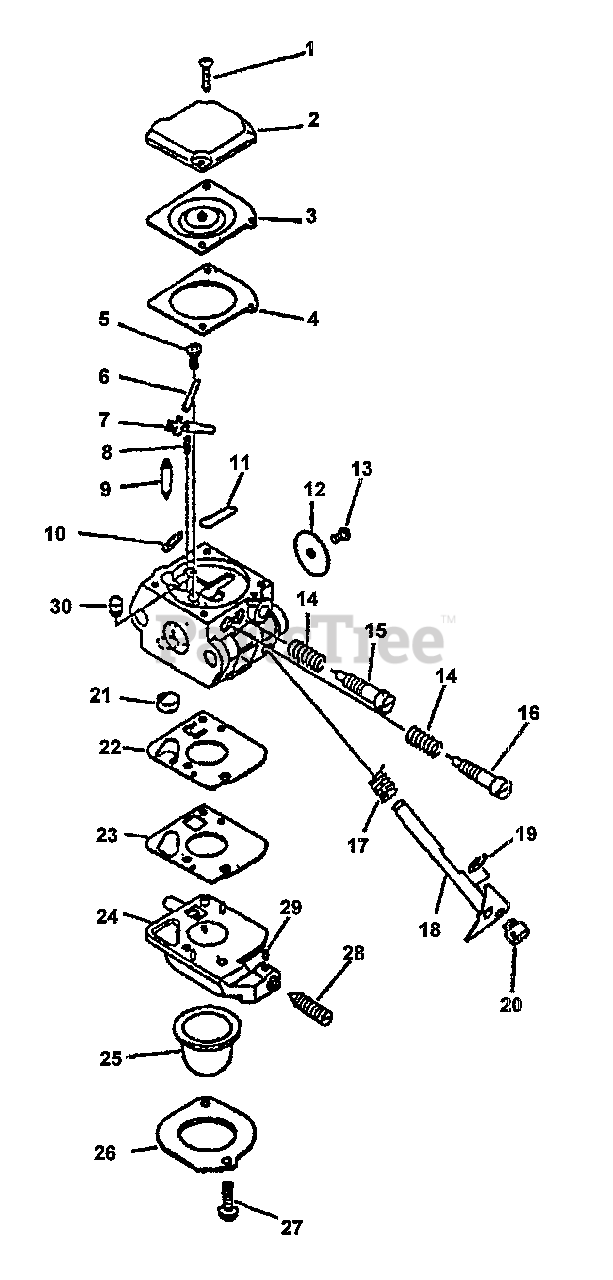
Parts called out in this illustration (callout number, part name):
2	COVER, METERING
3	DIAPHRAGM
4	GASKET, METERING
5	SCREW, METERING LEVER PIN
6	PIN, METERING LEVER
7	LEVER, METERING
8	SPRING
9	VALVE, INLET NEEDLE
10	RING, RETAINING
11	PLUG, WELCH
12	VALVE, THROTTLE
15	NEEDLE - MIXTURE
16	NEEDLE - HIGH SPEED
17	SPRING, RETURN
18	SHAFT, THROTTLE
19	RING, RETAINING
21	STRAINER
22	DIAPHRAGM, PURGE
23	GASKET, PURGE
24	BASE, PURGE
25	BULB, PURGE
26	RETAINER, PURGE BULB
27	SCREW, RETAINER
28	SCREW, IDLE ADJUST
29	PIECE, FRICTION
30	NOZZLE, CHECK VALVE
